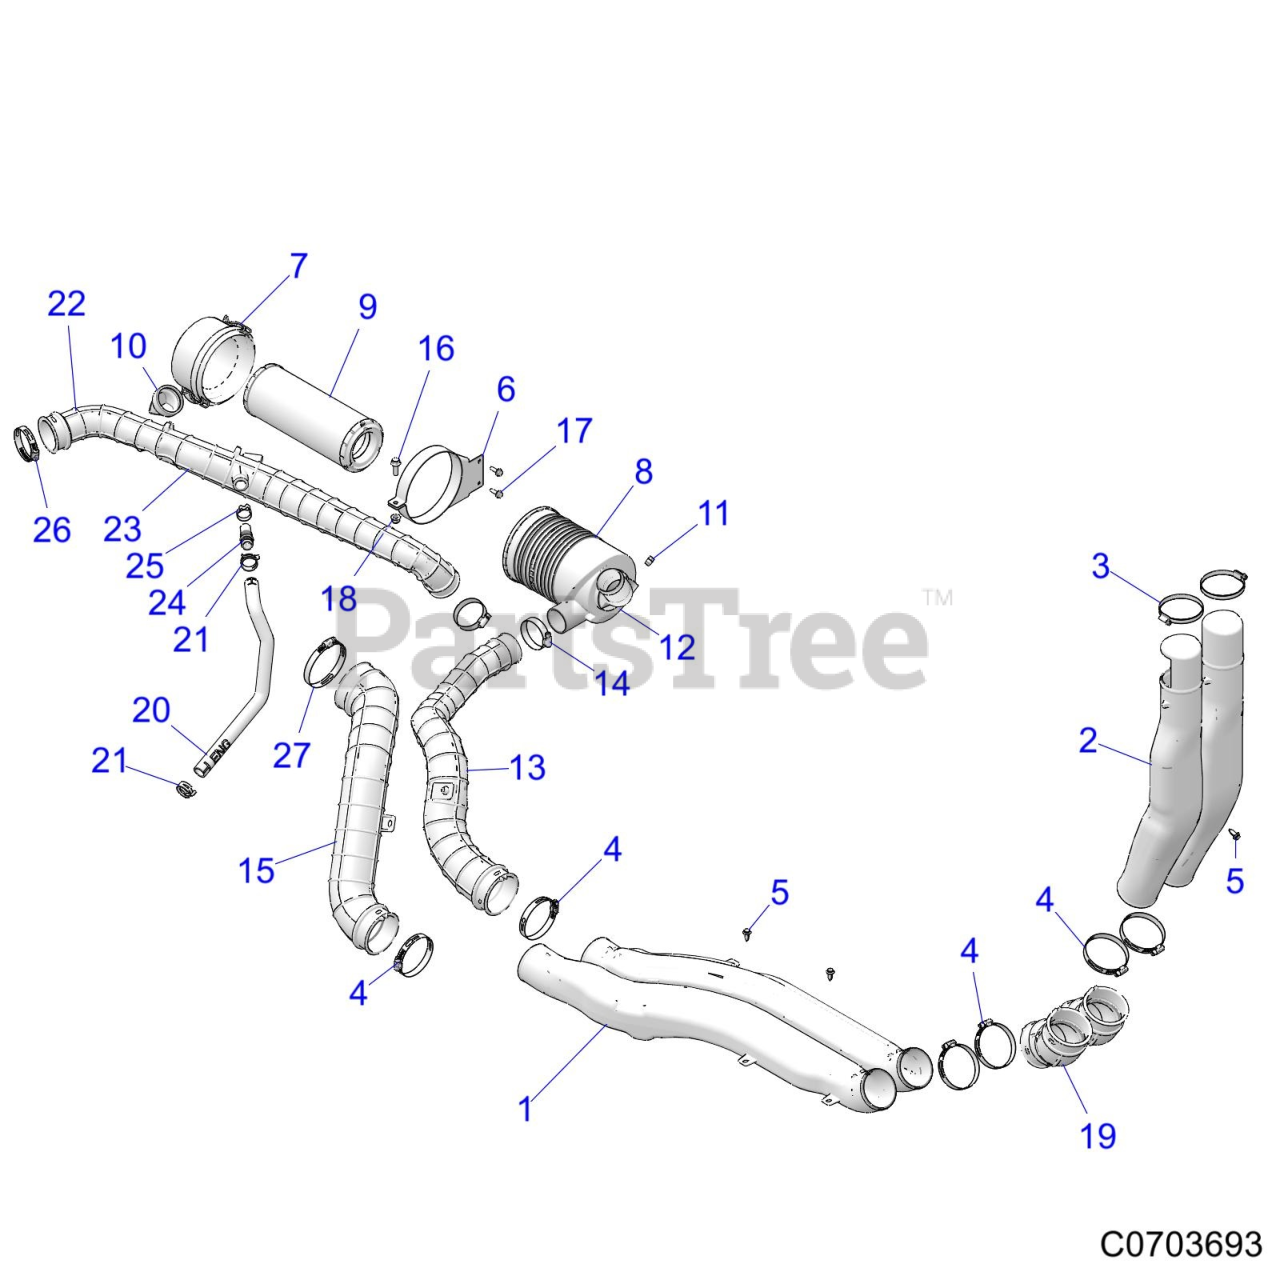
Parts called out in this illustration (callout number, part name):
1	DUCT-TUNNEL
2	DUCT-INTAKE,FRONT
3	CLAMP-BAND,NARROW 70-90MM
4	CLAMP-HOSE SLOTTED,75-90 DIA
5	RIVET-TUFLOK,.315-.325X.787 (5
6	WELD-MOUNT,AIRBOX
7	ASM-LID,AIRBOX
8	ASM., AIRBOX, MAIN
10	VALVE-AIRBOX
11	PLUG-AIRBOX
12	ASM-AIR INTAKE,ULTRAWEB
13	HOSE-INTAKE,PRE-FILTER
14	CLAMP, HOSE, S.S.(10)
15	HOSE-CLUTCH INLET TO TUNNEL
16	BOLT-M8X1.25X25,HXFLG-OLIVE D
17	SCR-M6X1.0X20,HXHD,FLG,TDFM,BL
18	NUT-M8X1.25,FLG,NYLOC-OLIVE D
19	HOSE-JOINT
20	HOSE-VENT,ENGINE
21	SPRINGBAND-CLAMP 27/12,GREEN
22	ASM-INTAKE,POST-FILTER
23	HOSE-INTAKE,POST-FILTER
24	FITTING-3/4 DOUBLE BARB
25	CLAMP-HOSE
26	CLAMP-HOSE SLOTTED,60-80 DIA
27	CLAMP-HOSE SLOTTED,89-100 DIA
